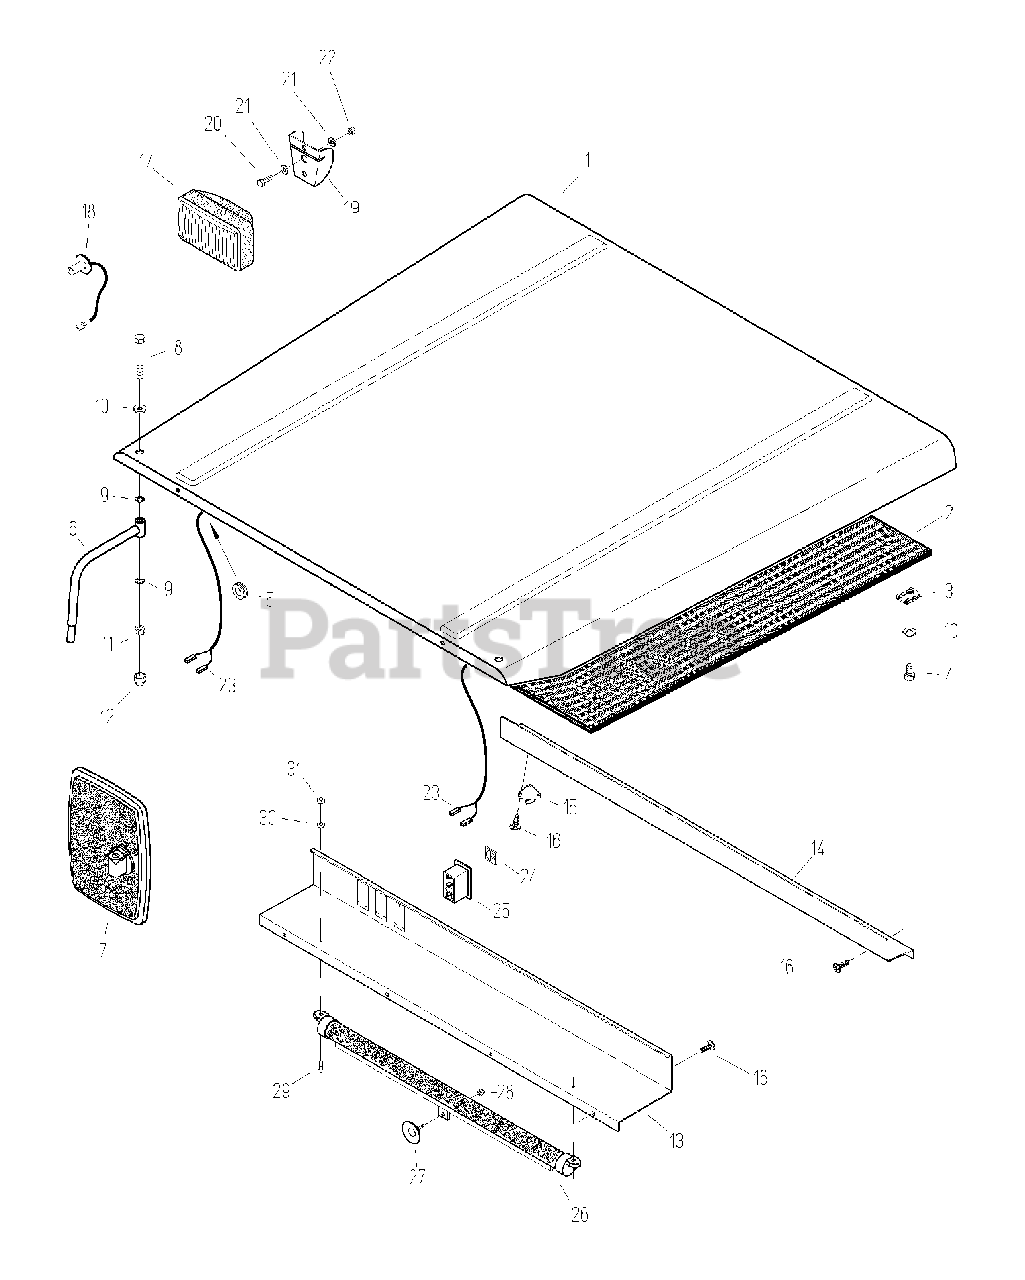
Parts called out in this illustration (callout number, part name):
2	INNER ROOF DECOR
3	NUT, M8 13965
5	CABLE GUIDE, 12MM
13	FRAME COVER, Front
14	FRAME COVER, Rear
15	COAT HANGER
16	SCREW, Self-Tapping Phillips Hd., 4.8 x 16
23	WIRING ASSEMBLY, Headlight
26	SHIELD, Sunlight
27	VAC SOCKET, with Screw
28	NUT, Cap M4
